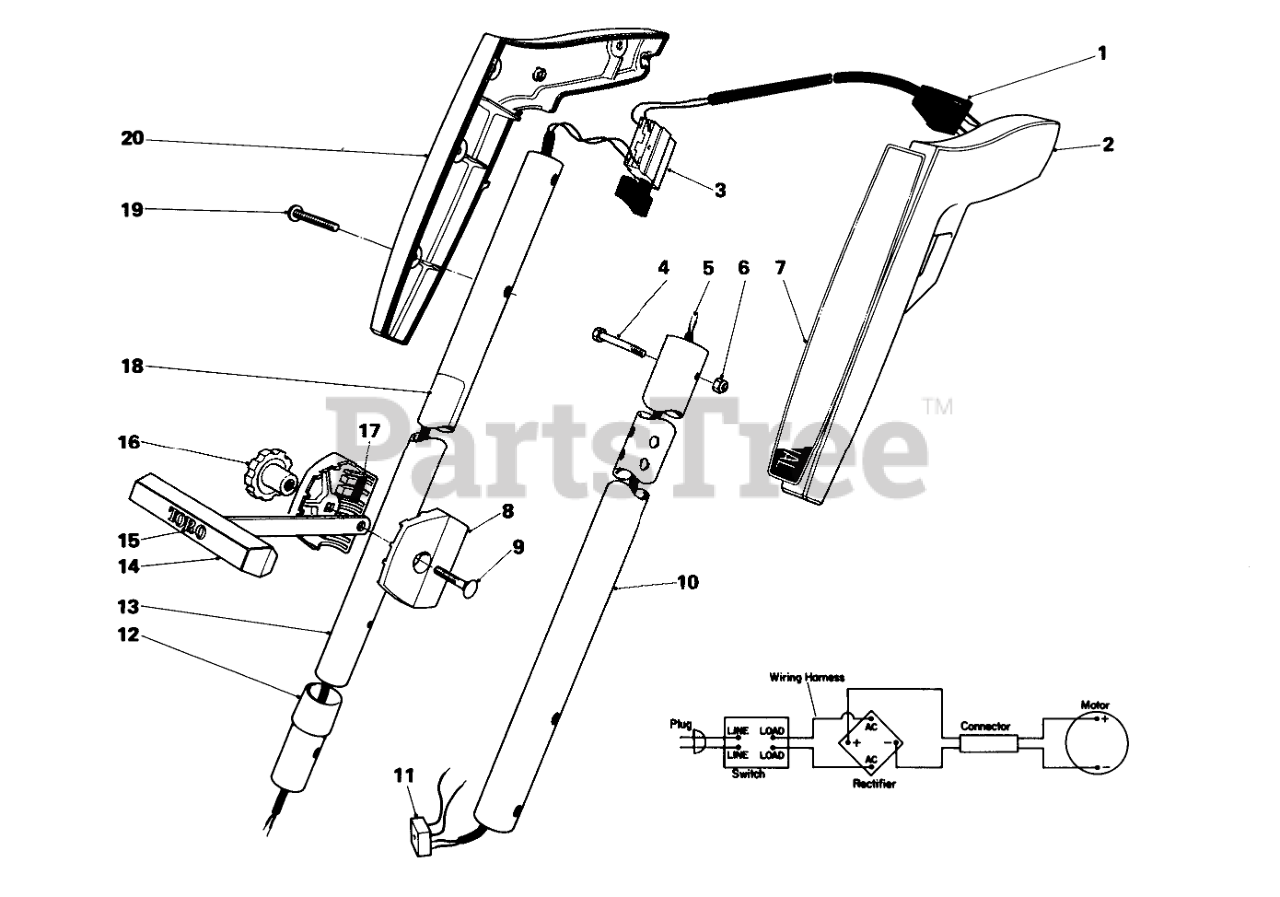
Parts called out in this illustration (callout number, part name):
1	Power Cord
2	Left Hand Grip
3	Two Speed Switch
4	Screw
5	Wiring Harness (Incl.Ref. #11)
6	NUT-LOCK, NI
7	Decal
8	Bracket
9	BOLT-CARR
10	Lower Tube
11	Rectifier
12	Tubing Sleeve
13	Tube-Upper
14	Tee Handle
15	DECAL - TORO
17	RUBBER INSERT
18	REPLACEMNT SERIAL PLT
19	Screw
20	Right Hand Grip
